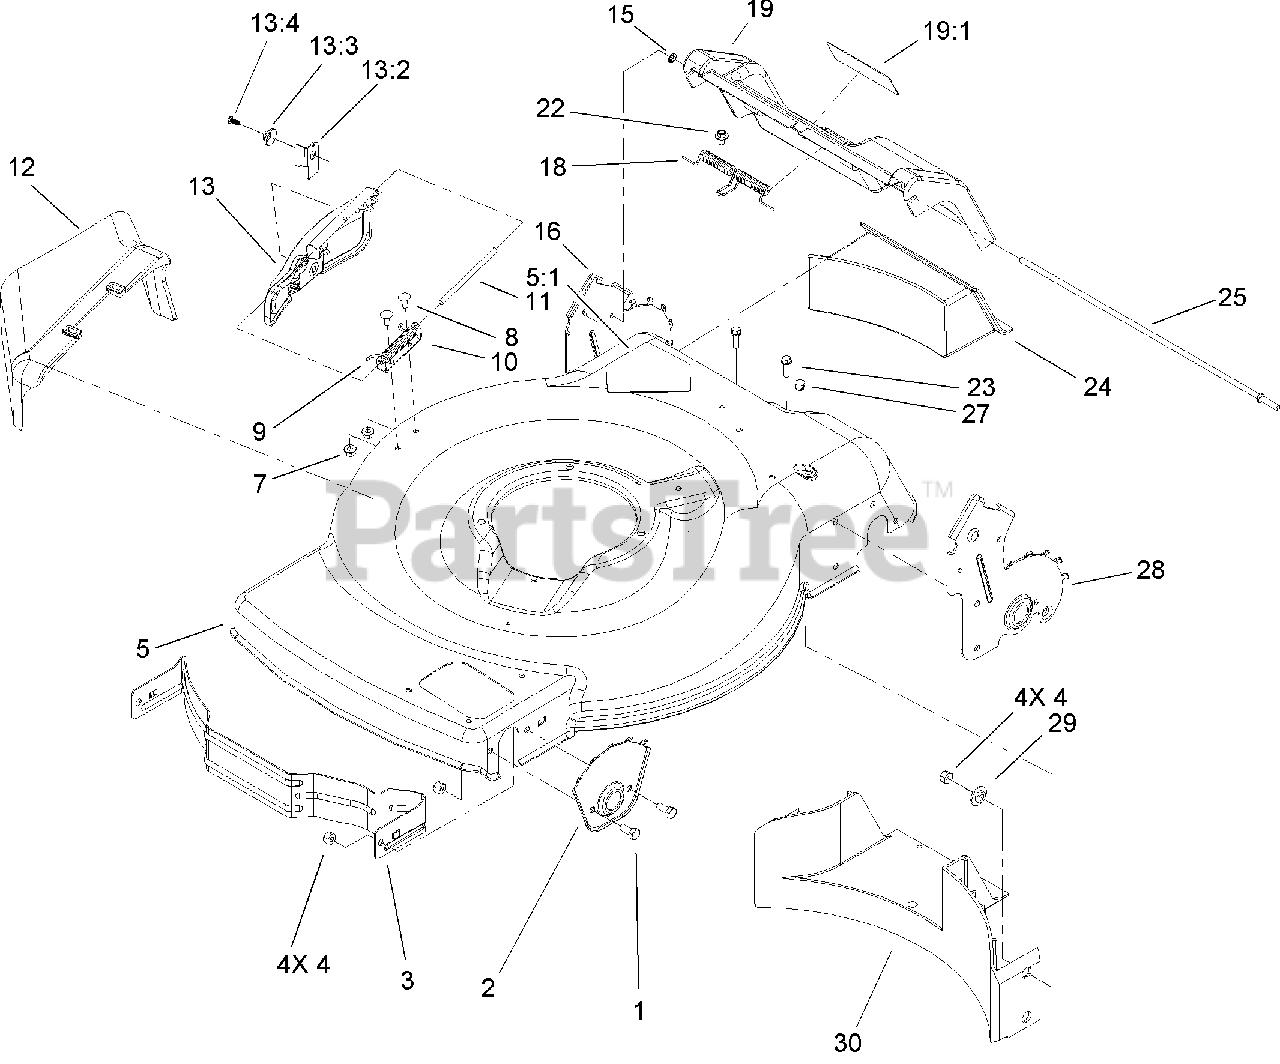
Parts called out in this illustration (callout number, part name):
1	SCREW-HH
2	Plate-HOC, Front
3	Baffle-Front
4	NUT-LOCK, NI
5	HOUSING ASM
5:1	DECAL-DANGER
8	SCREW-CARR
9	SPRING-TORSION
10	BRACKET-COVER
11	ROD-COVER
12	CHUTE-SIDE DISCHARGE
13	DISCHARGE DOOR ASM
13:2	LATCH-DOOR
13:3	CAP-DOOR
13:4	SCREW-PLASTITE
16	RH REAR HOC PLATE ASM
18	Spring-Door, Rear
19	DOOR ASM-SERVICE
19:1	DECAL-WARNING, DOOR
22	SCREW AND WASHER ASM
23	SCREW-HWH
24	Plug-Discharge, Rear
25	Rod-Pivot, Rear Door
27	Plug-Dome
28	LH REAR HOC PLATE ASM
29	Washer-Stepped
30	Baffle-Rear
